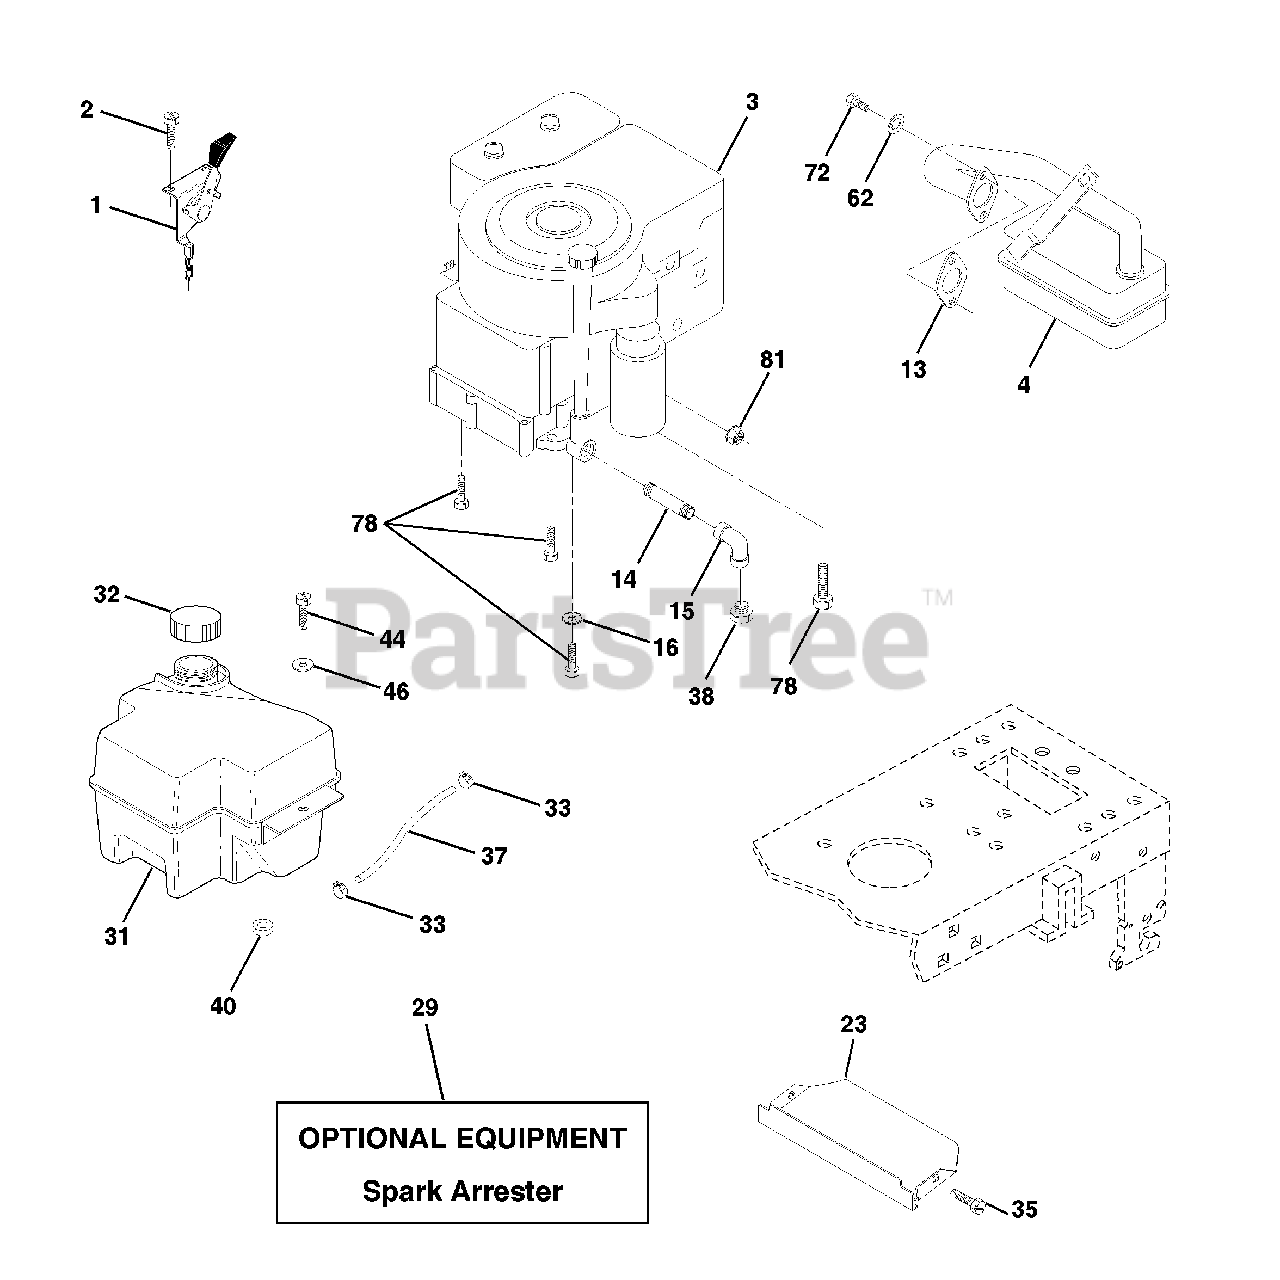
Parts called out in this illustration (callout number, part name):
1	Control Th/ch 23 5 LH Flag
2	Screw Hex Thd Cut 1/4-20 x 5/8 T
4	Muffler LT B&S 12/12.5/13HP
13	Gasket Eng 1 313 Id Tin Plated
14	Nipple Pipe 3/8 Npt X 3"
15	Elbow Std 90 Degree 3/8-18 Npt
16	Washer Lock Ext Tooth 3/8
23	shield Brn/Dbr Guard
29	Kit Spark Arrestor
31	Tank Fuel Front 2 00
32	Cap Asm Fuel W/sym Vented
33	Clamp Hose Black
35	Screw
37	Line Fuel 20"
38	Plug Oil Drain
40	Bushing Snap Nyl Blk Fuel Line
44	Screw Hexwsh Thdrol 1/4-20 x 3/4
46	Washer 9/32 X 7/8 X 16 Ga
62	Washer Lock Hvy Hlcl Spr 5/16
72	Screw Hexhd Cap 5/16-18 x 3/4
78	Screw Thdrol 3/8-16 x 1-1/4 TYTT
81	Nut Flange 1/4-20 Starter Nut
